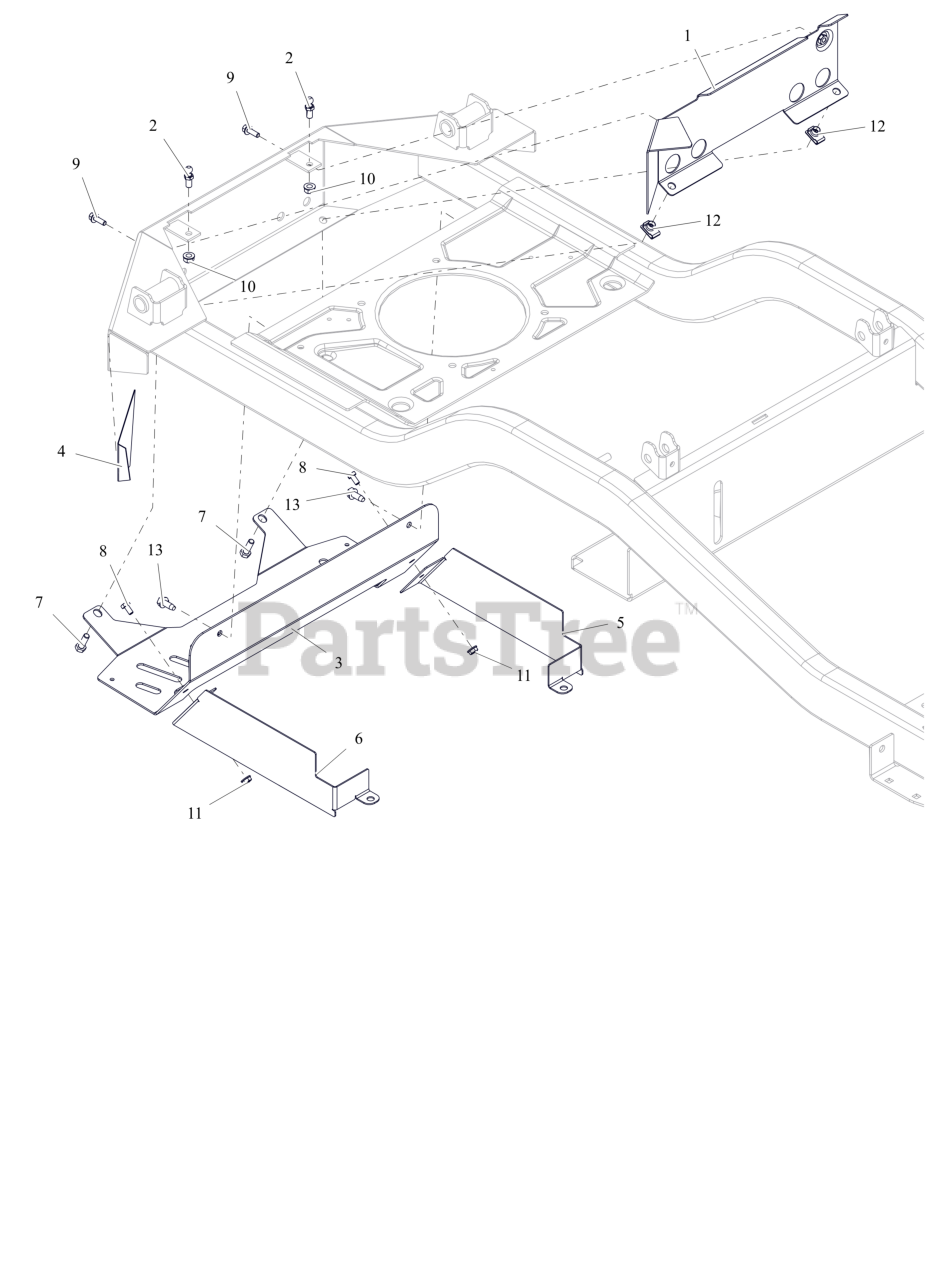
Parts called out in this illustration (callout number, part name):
1	WMT, HEAT BAFFLE
2	STUD- BALL
3	SHIELD, HEAT (HD) (BLACK)
4	TAPE, HEAT DEFLECTOR
5	GUARD,REAR CLUTCH LH
6	GUARD,REAR CLUTCH RH
7	BLT,HEX .31-18X1.00 G5 ZCC
8	BLT,HEX .25-20X.50 G5 ZCC
9	BLT,HEX-FLG .25-20X.75 G5 BFP
10	NUT,LK-CTR-FLG .31-18 GF ZCC
11	NUT-LK-TOP-FLG .250-20 GF ZCC
12	NUT-CLIP RETAINER 5/16-18X.56
13	SCR,TAP .312-18X.75 HWH TR ZCC
